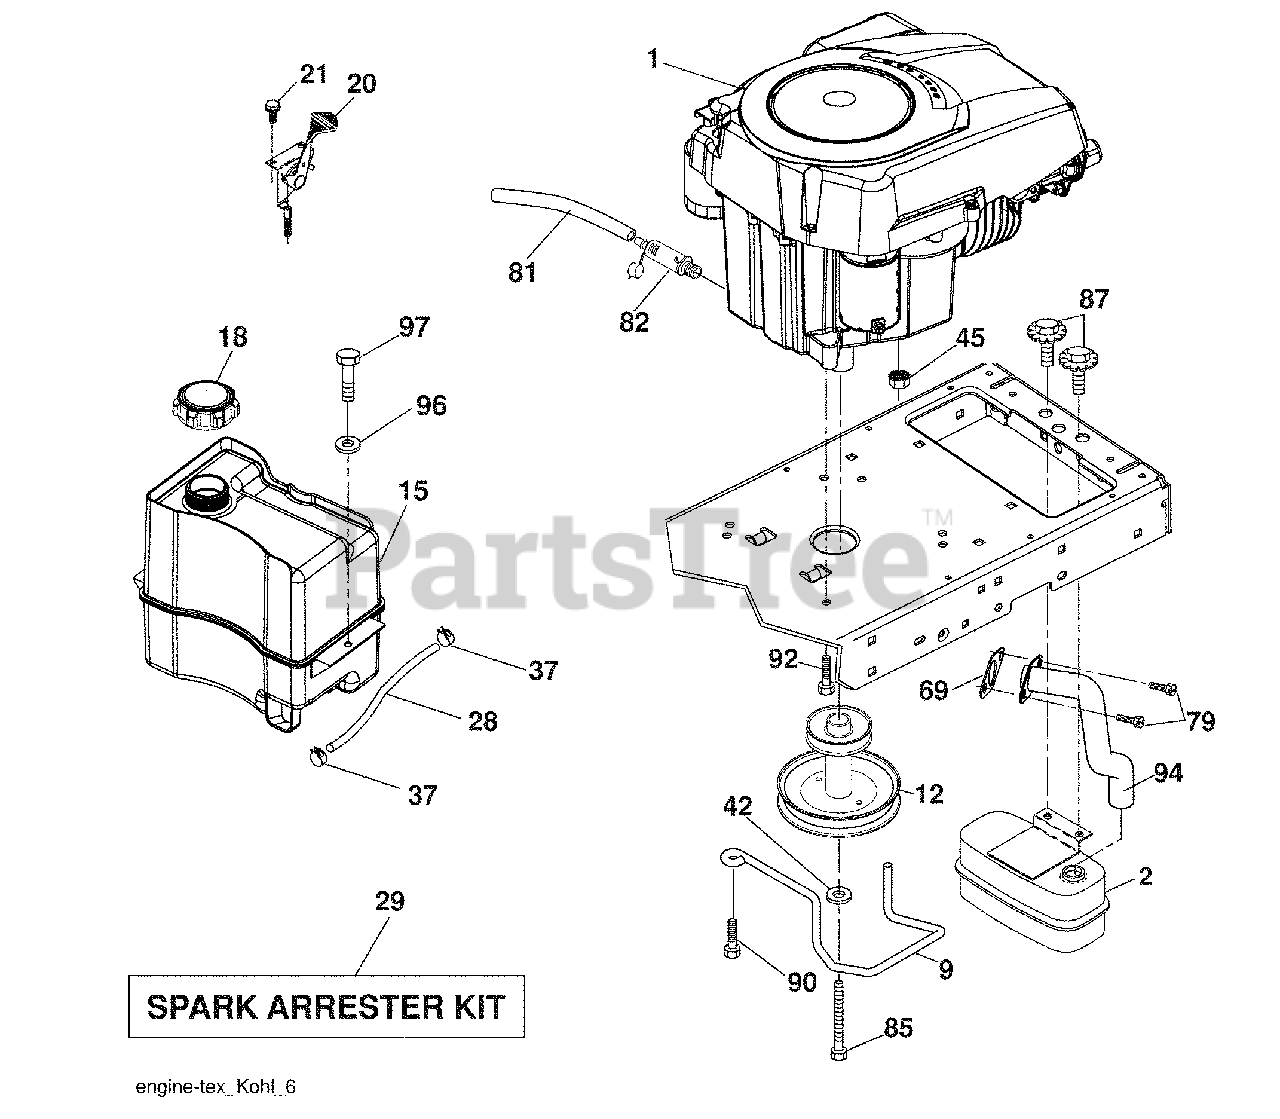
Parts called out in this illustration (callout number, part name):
9	Keeper Belt Engine
12	Pulley Engine
15	Tank Fuel
18	Cap Asm
20	Control Throttle
21	Screw #10 x 0.750
28	Fuel Line
29	Spark Arrester Kit
37	Clamp Hose
42	Washer Lock 7/16
45	Nut Keps Hex 1/4-20 unc
79	Screw Socket Hd. 5/16-18 x .75
81	Tube Drain Oil Easy
82	Plug Drain Oil
85	Bolt Hex 7/16-20 x 4 x Gr. 5-1.5 Thr
87	Bolt 5/16-18 unc x 3/4 w/Sems
90	Screw 3/8-16 x 1
92	Screw 3/8-16 x 1
94	Tube Exhaust
96	Washer 9/32 x 7/8 x 16 Ga.
97	Screw 1/4-20 x 3/4
